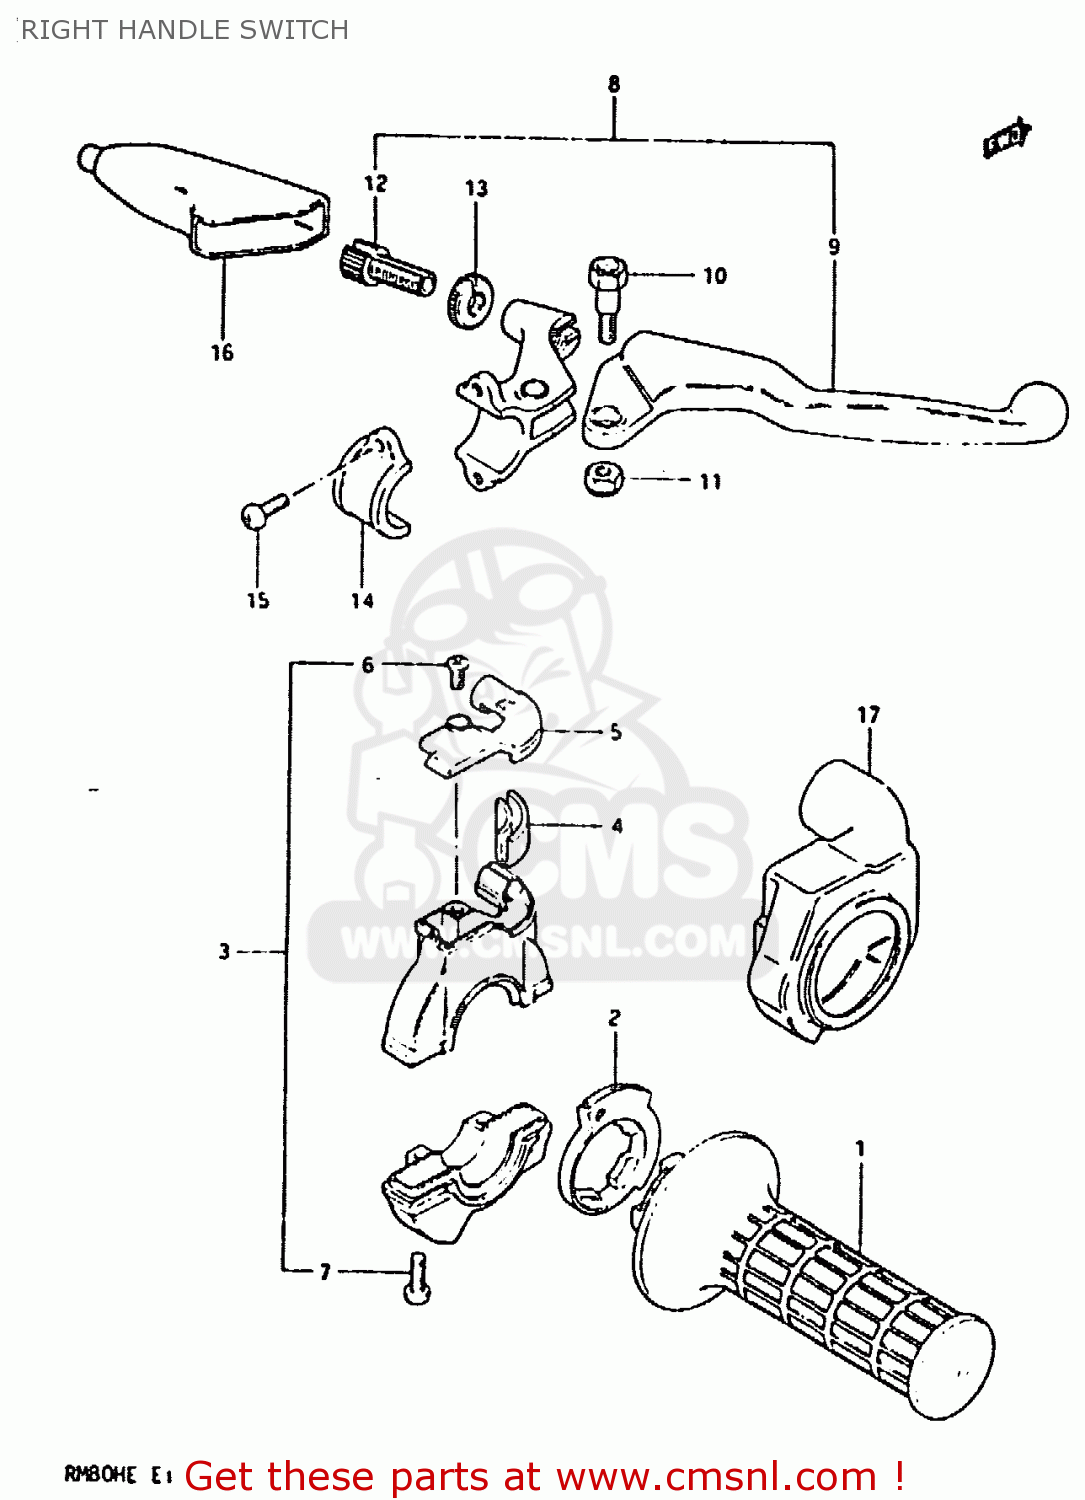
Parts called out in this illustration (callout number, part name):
1	GRIP,THROTTLE
2	ROTOR,THROTTLE GRIP
3	CASE ASSEMBLY,THROTTLE
4	GUIDE PIECE,THROTTLE
5	COVER,THROTTLE CASE
6	SCREW
7	SCREW
8	LEVER ASSY,BRAKE
9	LEVER,BRAKE
10	BOLT,LEVER
11	NUT 6MM
12	ADJUSTER,CABLE
13	NUT,CABLE ADJUSTER
14	BRACKET,CLUTCH LEVER HOLDER
15	SCREW
16	COVER,CLUTCH LEVER
17	COVER,THROTTLE CASE
